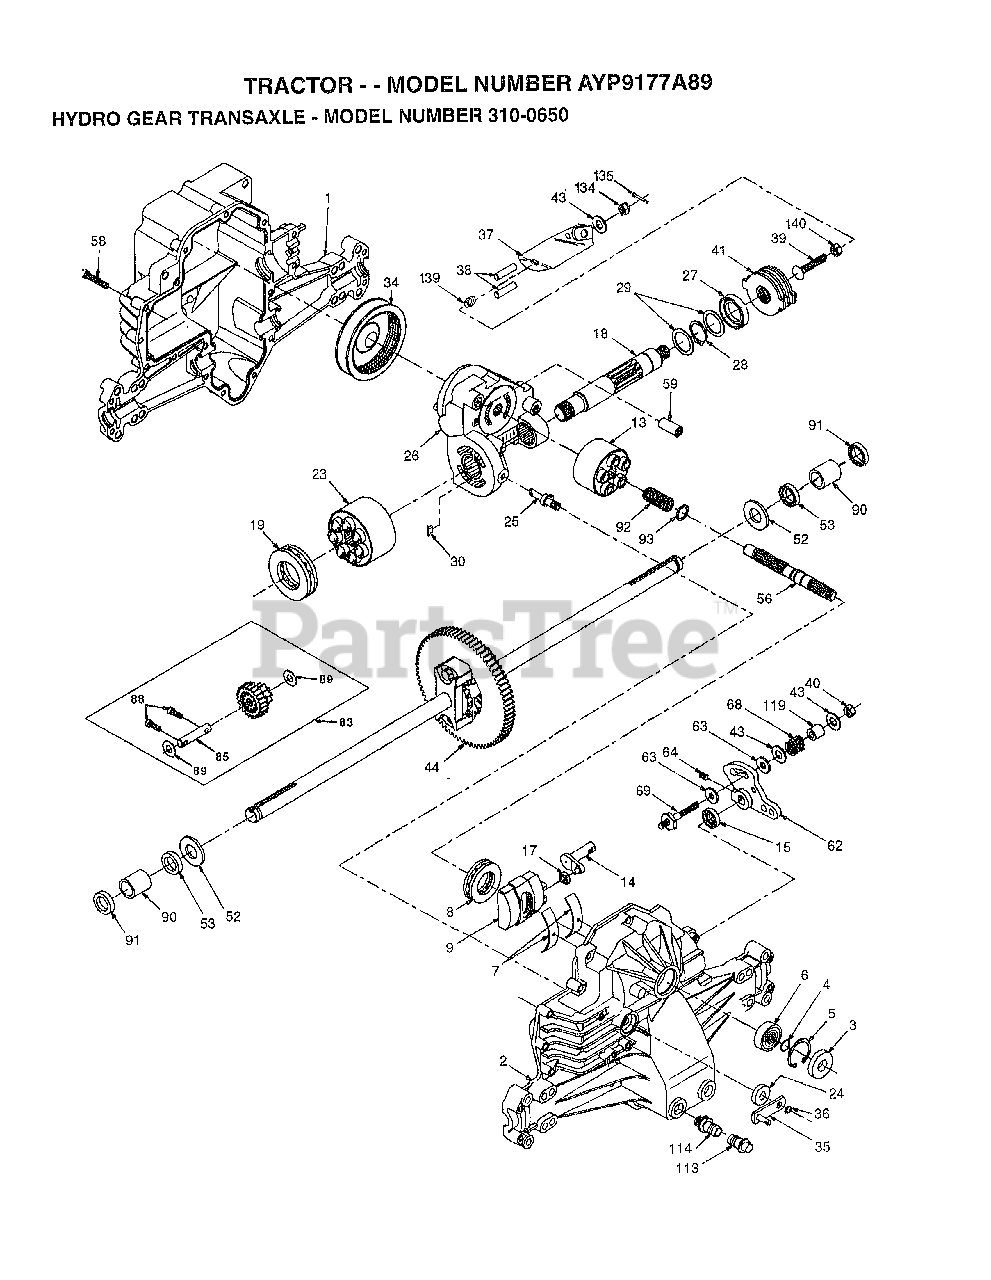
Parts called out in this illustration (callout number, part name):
1	HOUSING.L.50074RM
2	HOUSING.UP.70125
3	SEAL.9008000-0128
4	RING.RET.2003016.
5	RING.RET.2003052.
6	BEARING.(50552)42X68X16
7	CRADLE- 2003023.
8	BEARING.THU.50551
9	SWASHPLT.2003087.
13	BLOCK.CLYN.70079.
14	ARM.TRUN.2003005.
15	SEAL.9008000-0126
17	GUIDE.2000015.
18	SHAFT.MOTOR.50449
19	BEARING.THU.50552
23	BLOCK.CYLIN.70082
24	SEAL.LIP.45074
25	ACTUATOR.2003555
26	KIT.CEN.SEC.70250
27	SEAL.LIP.45075
28	RING RETAIN 50007
29	WASHER.44872
34	ELEMENT.OIL.44964
35	ARM.BYPASS.50270
36	RING.RETAIN.44870
37	ARM.ACTUAT.23710
38	PIN.ACTUAT.44891
39	BOLT.50316
40	NUT.LOCK.HX.50317
41	KIT.BRAKE.70135
43	WASHER HYD 44130
44	DIFFRENTIAL.70226
52	WASHER.HYD.44875
53	SEAL.HYDRO.45076
56	SHAFT.INPUT.50005
58	BOLT.1/4-20.44876
59	PIN.HYDRO.50002
62	ARM.CONTROL.50254
63	PUCK.DAMPER.50281
64	SCREW.SET.50018.
68	SPRING.HYD.50277
69	STUD.5/16-24.DANA
83	JACKSHAFT/PINION GEAR.70132
85	PIN.SHAFT 50559
88	SCREW.CAP.50154.
89	WASHER.HYD.50132
90	BEARING.SLV.50118
91	SEAL.WIPER.50941
92	SPRING.2003014.
93	WASHER.2003017
113	CAP.VENT.70109
114	O-RING.ASM.70110
119	SPACER.HYD.50278
134	NUT.CAS.HYD.44142
135	PIN.COT.HYD.44101
139	SPRING.COMP.50431
140	NUT.HEX.50269
